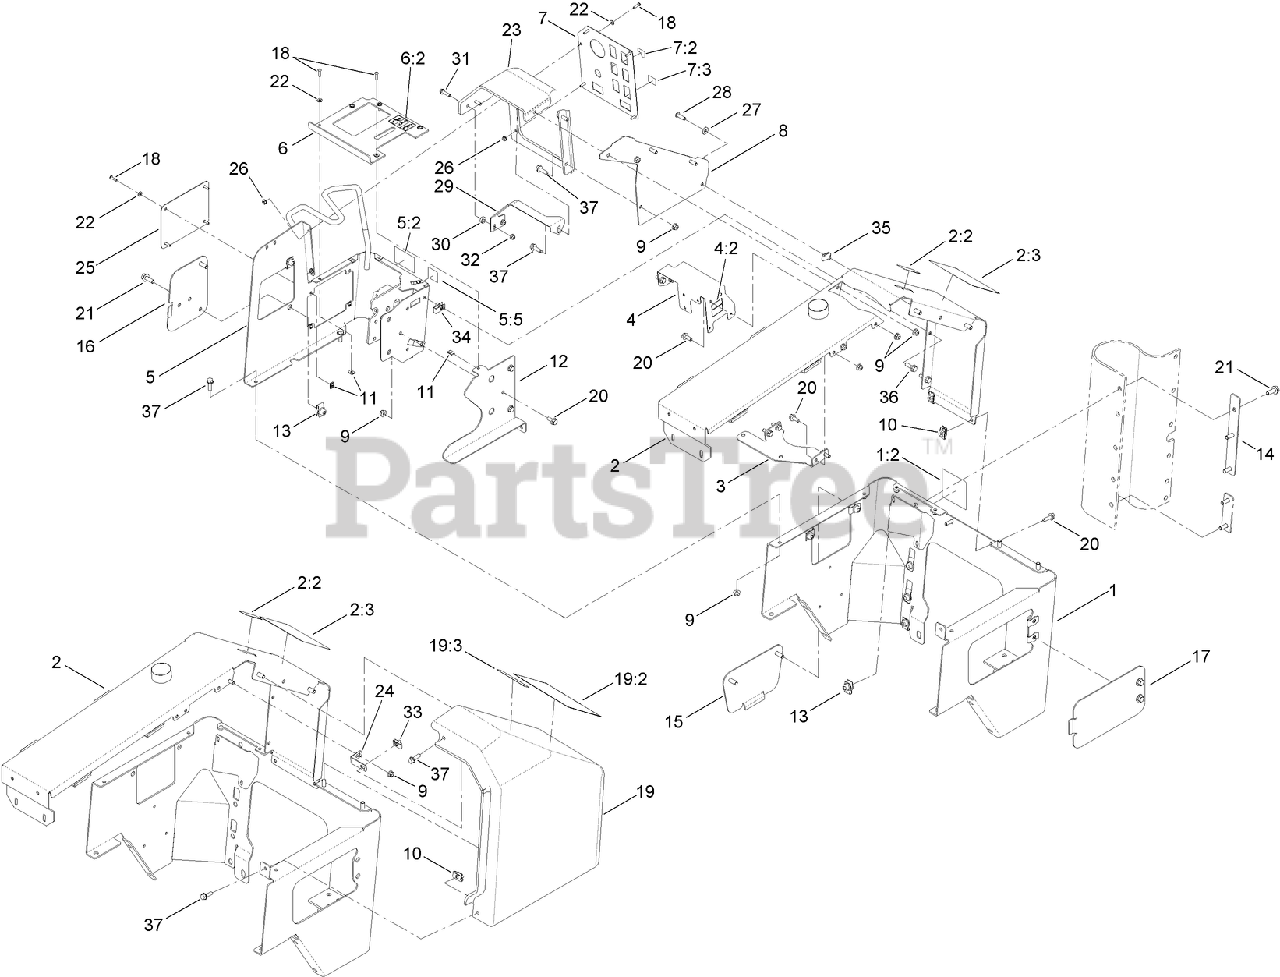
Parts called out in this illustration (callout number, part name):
1	LOWER CONSOLE ASM
1:2	DECAL-WARNING, SHIELD
2	CENTER CONSOLE ASM
2:2	DECAL-THROTTLE
2:3	DECAL-START UP, SHUT DOWN
3	BRACKET-AIR CLEANER
4	RELAY BRACKET ASM
4:2	DECAL-REGEN INHIBIT
5	UPPER CONSOLE ASM
5:2	DECAL-PARKING BRAKE
5:5	DECAL-GROUND DRIVE CONTROL
6	TOP CONTROL PLATE ASM
6:2	DECAL-ATTACHMENT LIFT
7	INSTRUMENT PANEL ASM
7:2	DECAL-ACK
7:3	DECAL-IGNITION
8	PLATE-CONTROLS, SIDE
9	NUT-HF, NI
10	NUT-THICK, TINNERMAN
11	NUT-SPEED
12	PLATE-TANK, HYD
13	Nut-Tinnerman
15	COVER-TRENCHER
16	COVER-SELECTOR
17	COVER-HYDRABORER
18	SCREW-HSBH
19	COVER ASM
19:2	DECAL-SAFETY
19:3	DECAL-ARRESTER, SPARK
20	SCREW-HHF
21	SCREW-HHF
22	WASHER-FLAT
23	PANEL-INSTRUMENT, PLASTIC
24	BRACKET-COVER
25	COVER-TRENCHER
26	NUT-LOCK, FLANGE
27	Washer
28	SCREW-HSH
29	BRACKET-SUPPORT, INSTRUMENT
30	SPACER
31	SCREW-HHF
32	NUT-HF
33	NUT-U
35	NUT-U
36	SCREW-HHF
37	SCREW-HHF
